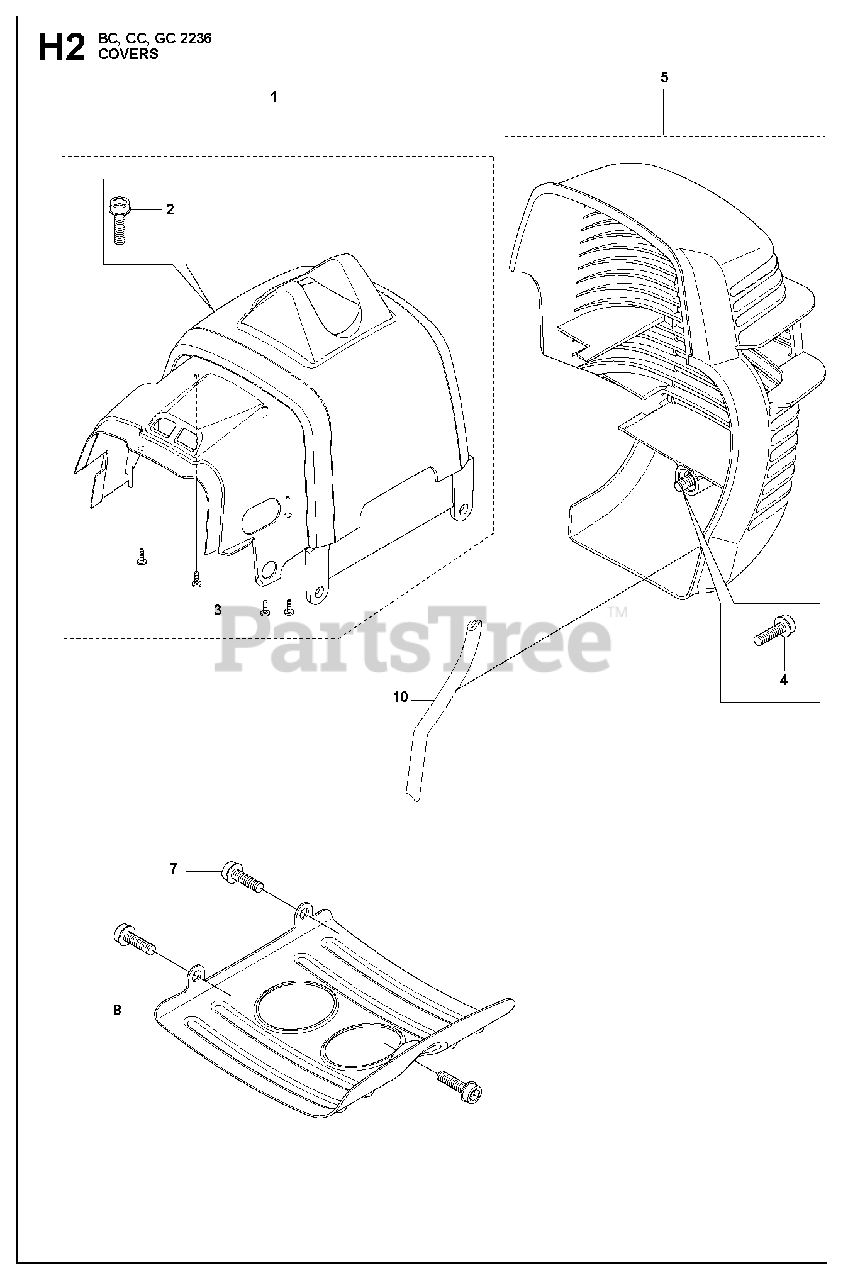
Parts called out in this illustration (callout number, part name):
1	CYLINDER COVER
2	SCREW IHSCFMO
3	SCREW
4	HEAT PROTECTOR
5	HEAT PROTECTOR
